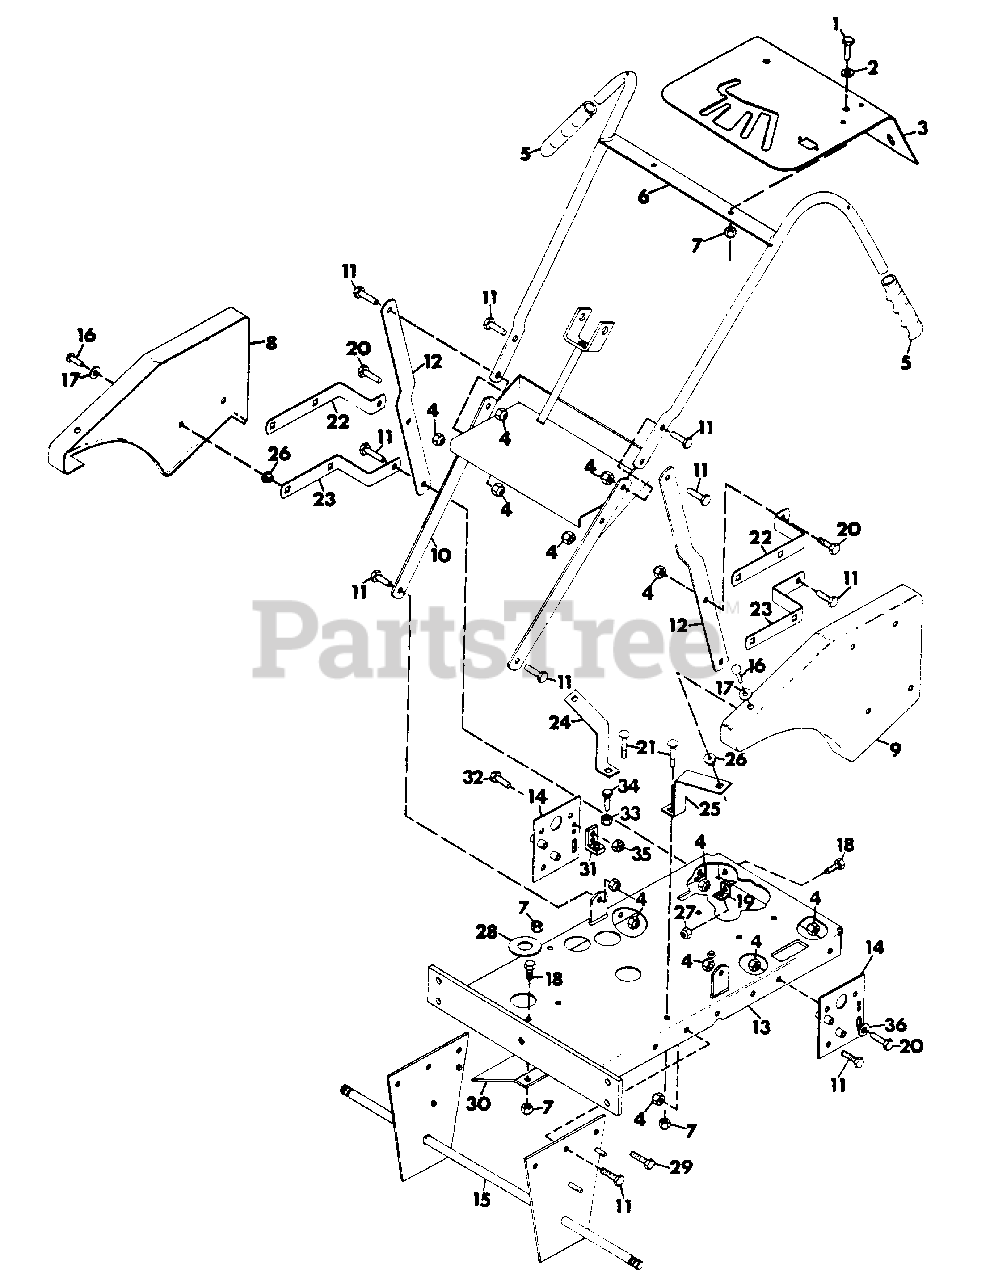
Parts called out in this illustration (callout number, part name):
1	BOLT, HEX 5/16-18X1.00
2	WASHER, FLAT .344X.688.X065
3	PLATE, INSTRUCTION
4	NUT, LOCK 3/8-16
5	GRIP, HAND
6	WELDMENT, HANDLEBAR
7	NUT, LOCK 5/16-18
8	GUARD, BELT R.H.
9	GUARD, BELT L.H.
10	WELDMENT, HANDLEBAR SUPPORT
11	BOLT, HEX 3/8-16X1.25
12	BRACE, HANDLEBAR SUPPORT
13	WELDMENT, FRAME
14	WELDMENT, BEARING SUPPORT
15	WELDMENT, AXLE
16	SCREW, MACHINE 1/4-20X.625 RD HD
17	WASHER, FLAT .281X.625X.065
18	BOLT, HEX 5/16-18X.625
19	TAB, SPRING
20	BOLT, HEX 3/8-16X1.00
21	BOLT, HEX 5/16-18X.75
22	BRACKET, TOP
23	BRACKET, BOTTOM
24	SUPPORT, FRONT R.H.
25	SUPPORT, FRONT L.H.
26	GROMMET, PLASTIC
27	NUT, LOCK 5/16-18
29	BOLT, HEX 3/8-16X1.50
31	BRACKET
32	BOLT, HEX 1/4-20X.75
33	NUT, HEX 1/4-20
34	BOLT, HEX 1/4-20X1.00
35	NUT, LOCK 1/4-20
36	WASHER, FLAT .406X.812X.065
NS	DECAL, AMERICA
